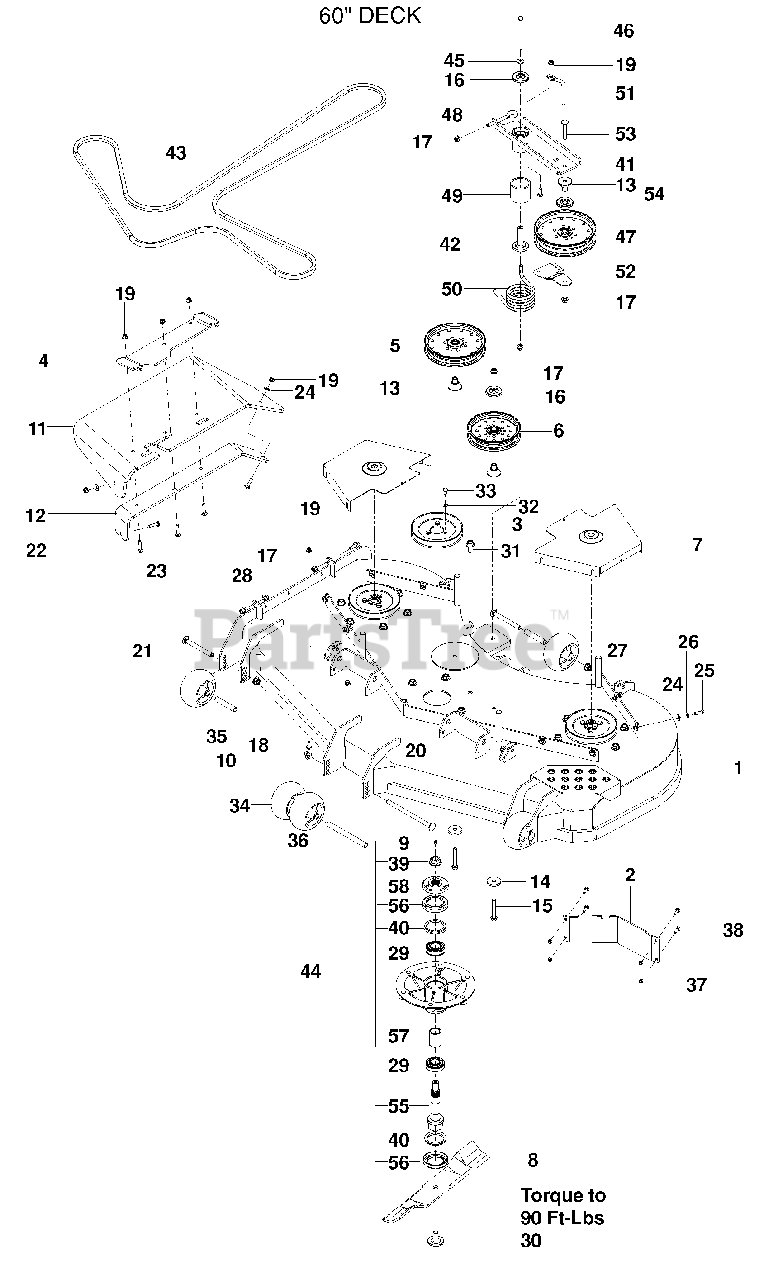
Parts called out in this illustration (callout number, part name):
1	Deck W/ Safety Decals
2	Bolt 7/16-20 X 1 1/2 Hex Nyl
4	Bracket, Chute Pivot
5	Pulley, Idler 7" Narrow
6	Pulley, Idler, 6"
7	Shield, Belt
8	Blade, 21"
9	Zerk
10	Nut 1/2-13 Hex Flg Nyloc
11	Chute, Discharge
12	Bracket, Chute Support
13	Bearing, Idler Arm
14	Washer, Heavy
15	Screw 3/8-16 X 2 3/4 Hex Flg
16	Shield, Dust
17	Nut 3/8-16 Hex Flg Nyloc
18	Screw 5/16-18 X 3/4 Hex Flg
19	Nut 5/16-18 Hex Flg Nyloc
20	Bolt 1/2-13 X 8 Rd Hd
21	Bolt 1/2-13 X 4 3/4 Rd Hd
22	Bolt 5/16-18 X 1 1/2 Rd Hd
23	Bolt 5/16-18 X 1 1/4 Rd Hd
24	Washer 5/16 Std Flt
25	Bolt 5/16-18 X 1 Hex Hd
26	Washer 5/16 Slw
27	Retainer, U Type
28	Screw 3/8-16 X 1 Hex Flg
30	Blade Bolt
31	Screw 1/2-13 X 1 Hex Flg
32	Washer 5/16 Disc Spring
33	Bolt 5/16-18 X 1/2 Hex Nyloc
34	Roller, Gauge
35	Tube, Roller Axle
36	Tube, Roller Axle Long
37	Nut 1/4-20 Hex Nyloc
38	Bolt 1/4-20 X 3/4 Carriage
39	Nut 3/4-16 Flg
41	Arm, Idler W/ Brgs, Spacr
42	Bearing, Idler Pivot
43	Belt, Deck
44	Spindle Assy
45	Washer 3/8 Thick
46	Bolt 3/8-16 X 4 1/2 Hex Gr 8
47	Pulley, Idler 7" Wide
48	Eyebolt 3/8 X 4
49	Spacer, Idler Pivot
50	Spring, Torsion
51	Keeper, Belt
52	Guide, Belt
53	Bolt 3/8-16 X 2 1/2 Carriage
54	Bolt 5/16-18 X 1 Rd Hd
55	Shaft, Spindle
56	Cup, Debris
